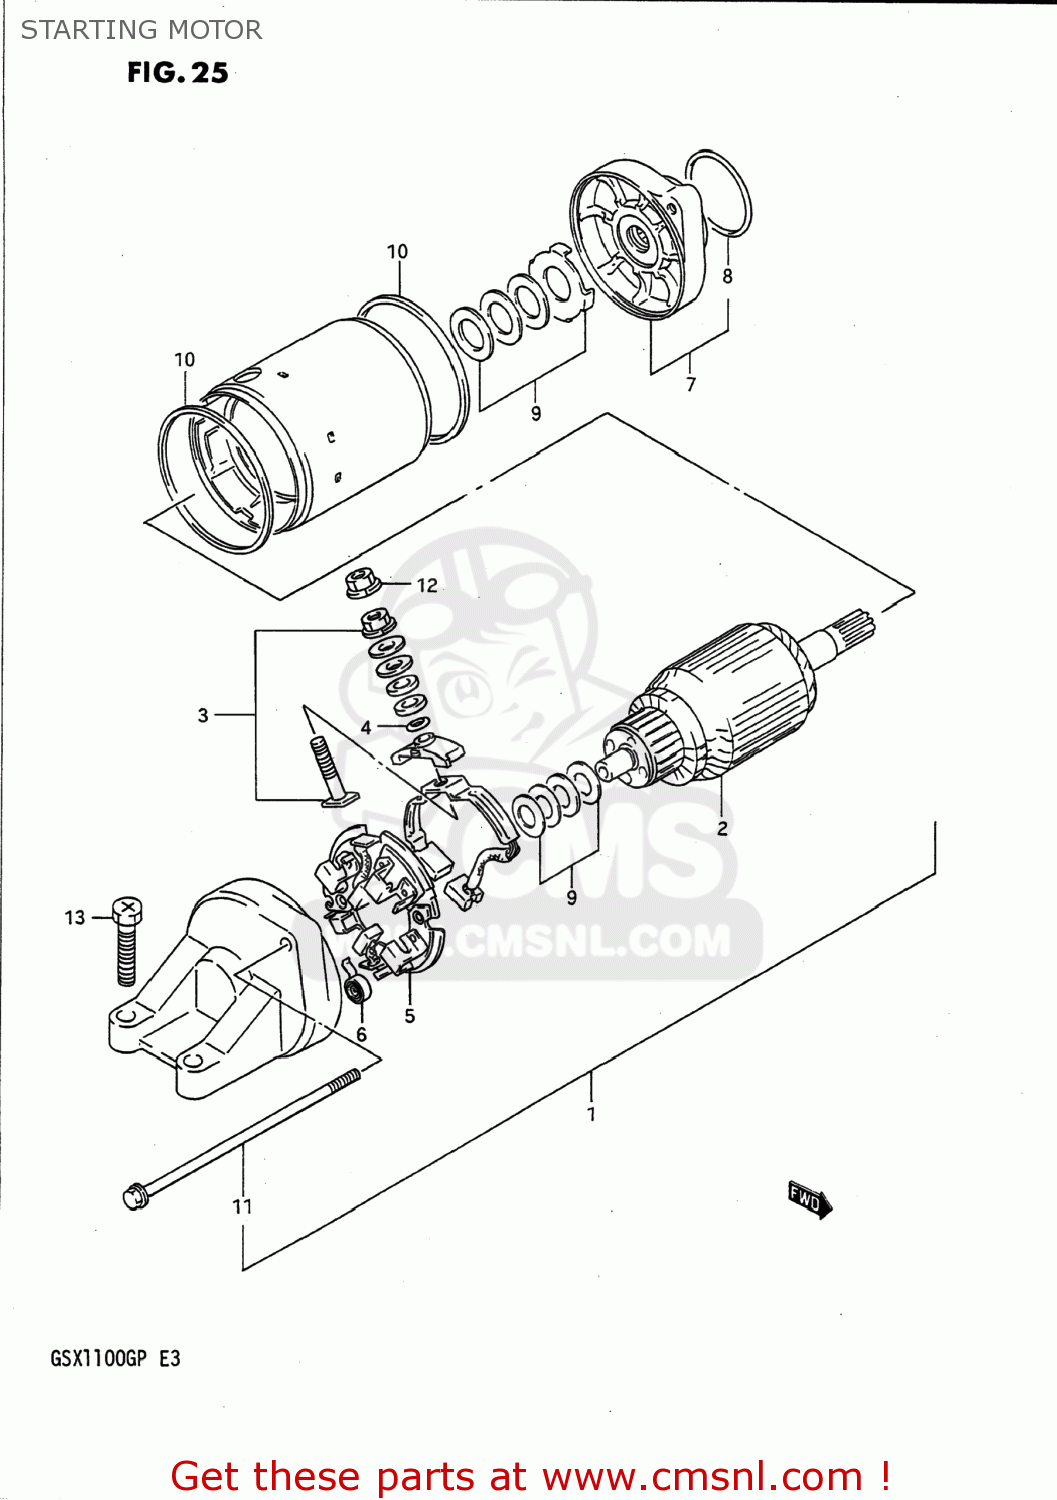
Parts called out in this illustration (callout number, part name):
1	MOTOR ASSEMBLY,STARTING (SI
2	ARMATURE
3	TERMINAL SET,BRUSH
4	O RING
5	HOLDER SET,BRUSH
6	SPRING,BRUSH
7	BRACKET ASSY,FR
8	O-RING
9	SHIM SET,STARTING MOTOR
10	O RING
11	BOLT
12	NUT
13	SCREW (6X25)
